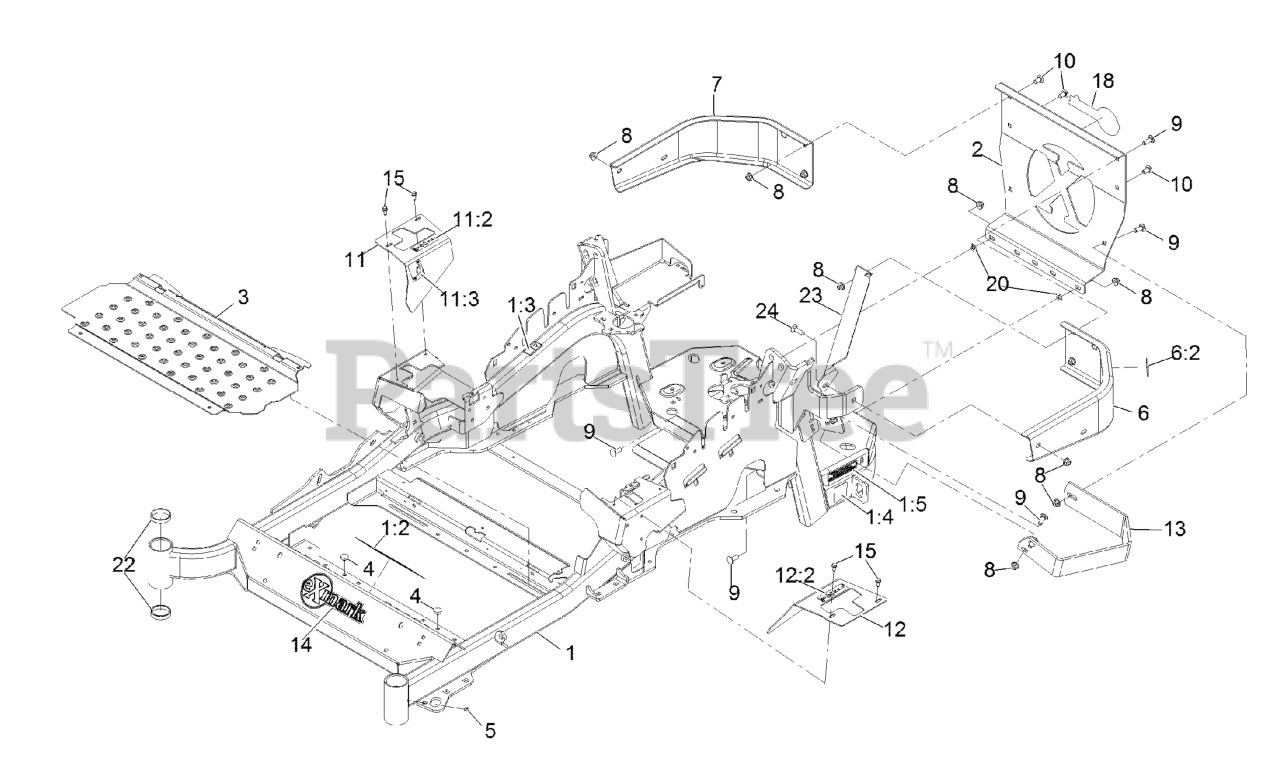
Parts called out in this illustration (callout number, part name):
1	MAINFRAME ASM
1:2	DECAL-DANGER
1:3	DECAL-WARNING
1:4	DECAL-HAZARD, PINCHED FINGER
1:5	DECAL-SPARK ARRESTER
2	PLATE,REAR GUARD
6	LH BUMPER ASM
6:2	DECAL-WARNING
7	BUMPER-RH
8	NUT-HF, NI
9	SCREW-CARR
10	SCREW-CARR
11	RH MOTION CONTROL COVER ASM
11:2	DECAL-CONTROL, MOTION
11:3	DECAL-PARK BRAKE, CE
12	LH MOTION CONTROL COVER ASM
12:2	DECAL-CONTROL, MOTION
13	GUARD-MUFFLER
14	DECAL-EXMARK LOGO
15	SCREW-HWH
18	DECAL-EXMARK LOGO
19	Decal-Patent Ttco.Com
20	NUT-PUSH
21	DECAL-FUEL FILL, CE
22	CUP-BEARING
24	BOLT-CARR
